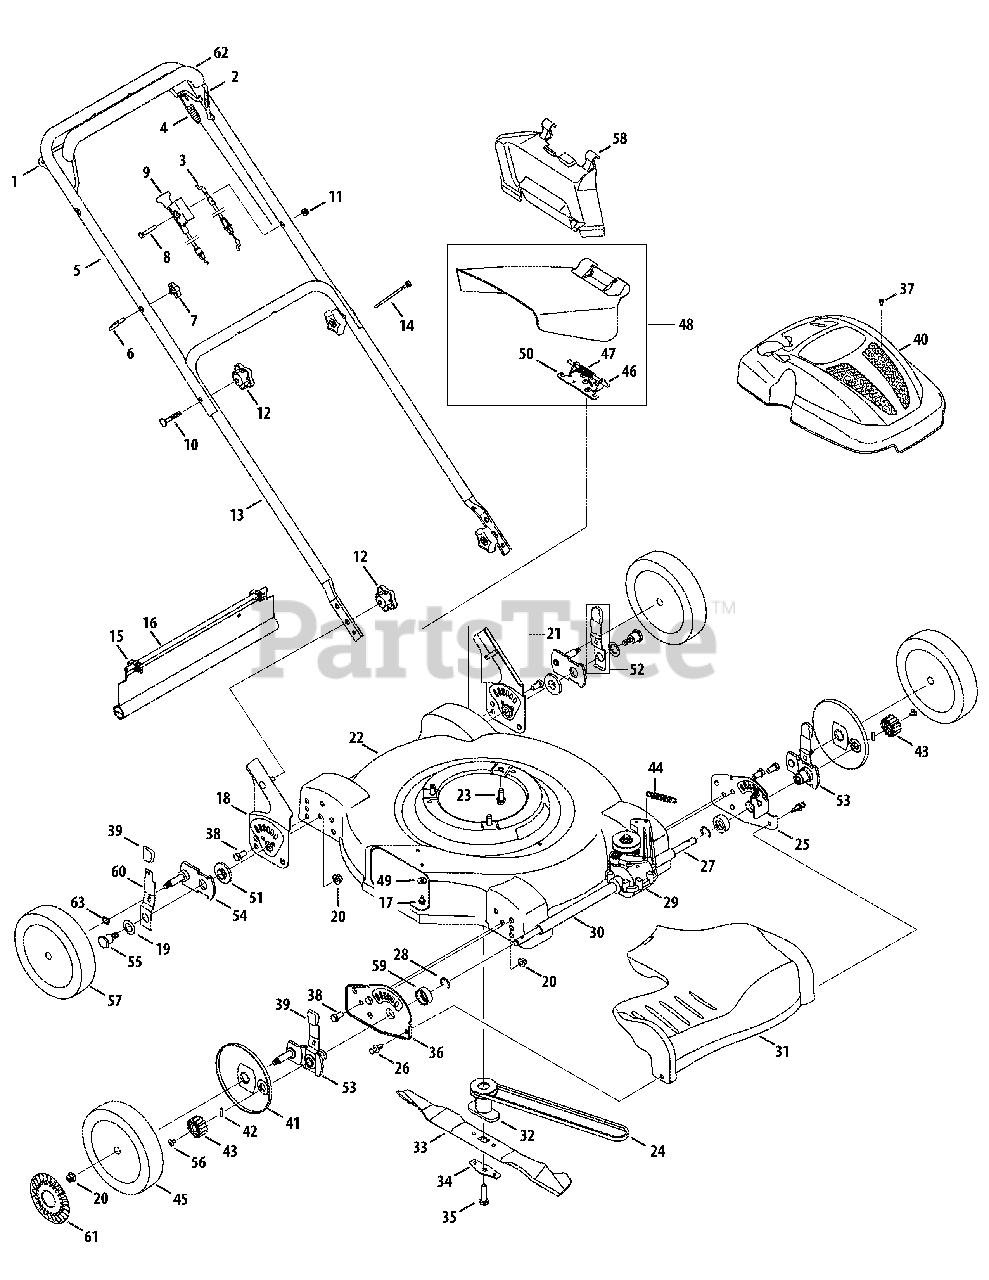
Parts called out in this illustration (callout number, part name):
1	Dive Control
3	Blade Control Cable
4	Drive Control Cable
6	Eye Bolt
7	Wing Nut, 1/4-20
8	Hec Screw, 1/4-20 x 1.50
9	Choke Cable
10	Carriage Boltm 5/16-18 x 2.0
11	Flange Lock Nut, 1/4-20
12	Star Knob
14	Cable Tie
15	Hinge Clip
16	Trail Shield
17	Hec Screw, 1/4-20 x .500
20	Lock Nut, 3/8-16
23	Hex Washer Scr., 3/8-16 x 1.0
24	V-Belt, 3L x 32.90
26	Rivet
27	Sleeve Spacer, .550 ID x 2.22
28	Retainer Ring
29	Transmission Assembly Complete
30	Sleeve Spacer, .550 ID x 8.51
31	Transmission Cover
32	Blade Adapter
33	22'' Mulching Blade
34	Blade Bell Support
35	Hex Cap Screw, 3/8-24 x 1.5
37	Machine Screwm M4X.7
38	Hex Cap Screw, 3/8-16 x .75
39	Adjustment Knob
40	Engine Shroud
41	Wheel Dust Cover
42	Pin
43	Spur Gear 14T - RH
43	Spur Gear 14T - LH
44	Ext. Spring, .4 OD x 2.50
45	Front Wheel, 8 x 1.8
45	Front Wheel, 8.x2.125
46	Hinge Pin
47	Torsion Pin
48	Side Discharge Assembly
49	Bell Washer, .265 ID x .75 OD
50	Deflector Chute Adapter
51	Height Adjustment Bearing
52	Rear Height Adj. Lever Assembly
53	Front Lever Assembly
54	Rear Pivot Arm Assembly
55	Shoulder Screw, 3/8-16
56	Screw, 1/4-20 x .390
57	Rear Wheel, 8 x 1.8
57	Rear Wheel, 8.2.125
58	Mulching Baffle
59	Bearing Support Spacer
60	Spring Lever
61	Hub Cap
62	Deluxe Bail Cover
63	Washer, Wave, .510 x .750 x .017
